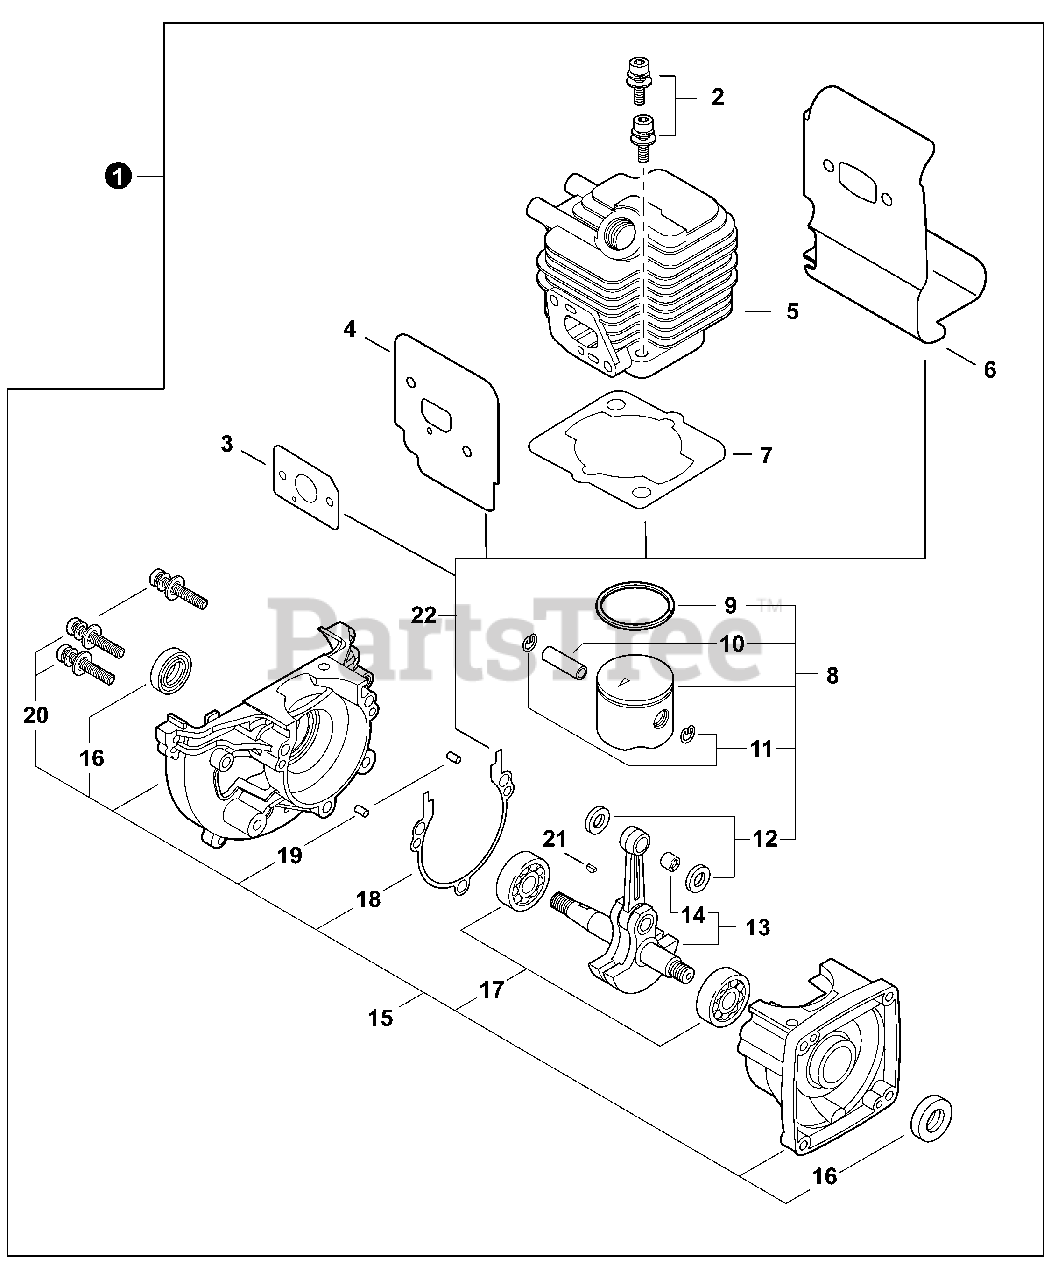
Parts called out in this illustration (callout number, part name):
1	SHORT BLOCK
2	BOLT 5×22
3	GASKET, INTAKE
4	HEAT SHIELD, INTAKE
5	CYLINDER
6	HEAT SHIELD, EXHAUST
7	GASKET, CYLINDER
8	PISTON KIT
9	RING, PISTON
10	PIN, PISTON 8
11	RING, RETAINING
12	WASHER, THRUST
13	CRANKSHAFT ASSY
14	BEARING, NEEDLE 8
15	CRANKCASE KIT
16	SEAL, OIL 12
17	BEARING, BALL
18	GASKET, CRANKCASE
19	PIN, LOCATING 4×8
20	BOLT 5×28
21	KEY, WOODRUFF
22	GASKET KIT: ENGINE, INTAKE, EXHAUST
